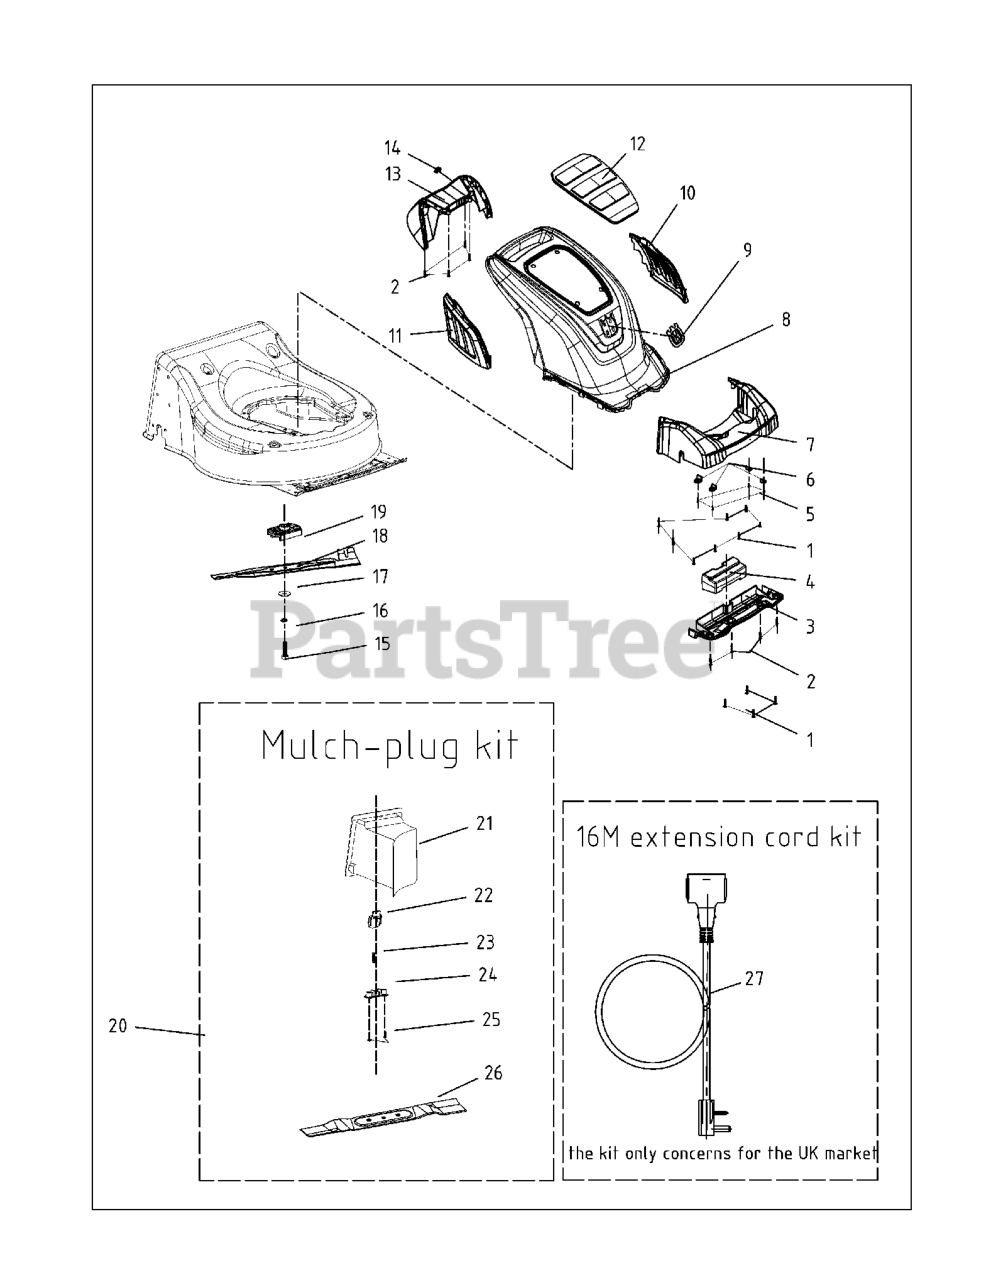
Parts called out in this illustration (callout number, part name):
3	COVER FRONT HANDLE (UNDER SIDE
4	WEIGHT # 25100184101
7	COVER FRONT COVER
9	DECAL LOGO
13	COVER BACK COVER
16	SPRING WASHER
18	MOWER BLADE MULCH 40CM PRODUCT
19	BLADE SUPPORT
21	PLUG 25232600101
26	BLADE 26300349801
